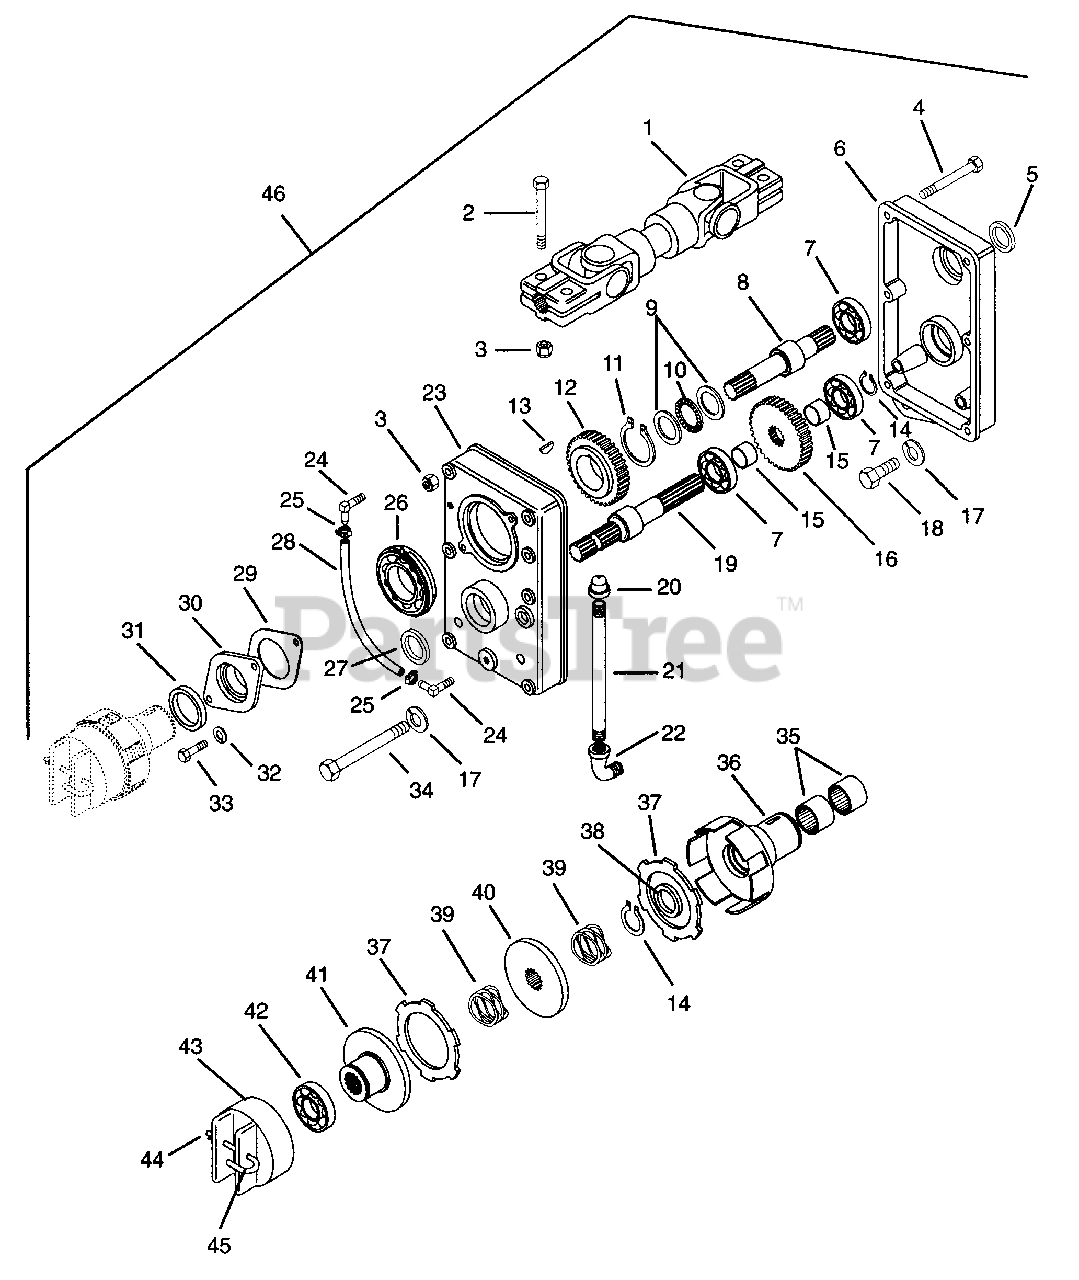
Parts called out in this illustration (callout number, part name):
1	Assembly, PTO U-Joint
2	Bolt-Hex .38-16 x 1.75 Grade 5
3	Nut-Locking-Center .38-16
4	Bolt-Hex .38-16 x 3.50 Grade 5
5	Seal .984 x 1.6 x .25
6	Case, PTO
7	Bearing-Ball .984 x 2.047 x .591
8	Shaft, PTO Input
9	Washer-Thrust 1.55
10	Bearing-Needle-Thrust 1.0 x 1.55 x .078
11	Ring-Retaining-External 1.819 x .062
12	Gear, PTO
13	Key-Woodruff .25 x 1
14	Ring-Retaining-External .906 x .078
15	Spacer 1.01 x 1.25 x .645
16	Gear, PTO
17	Washer-Locking .50 X 1.25
18	Bolt-Hex .50-13 x 1.50 Grade 5
19	Shaft, PTO
20	Cap, Pipe 3/8"
21	Nipple, Pipe .38 x 6.0
22	Elbow .38 x 90
23	Cover
24	Elbow, Hose
25	Hose Clamp
26	Bearing-Ball 1.97 x 3.14 x .63
27	Seal 1.25 x 1.75 x .25
28	Hose, 1/4 Inch Vinyl
29	Gasket, Front PTO Cap
30	Cap, Front PTO
31	Seal 2.250 x 3.002 x .375
32	Washer-Lock .31 x .078
33	Bolt-Hex .31-18 x .75 Grade 5
34	Bolt-Hex .50-13 x 4.25 Grade 5
35	Bearing-Roller 1.0 x 1.312 x .75
36	Hub, PTO Clutch
37	Disc, Clutch
38	Seal 1.0 x 1.50 x .25
39	Spring-Wave
40	Plate, Clutch
41	Hub, Clutch Actuating
42	Bearing-Ball 1.57 x 3.15 x .71
43	Trunion, Forward-Reverse Clutch
44	Pin-Cotter .062 x .75
45	Pin, Clutch Spring
46	PTO Assembly
